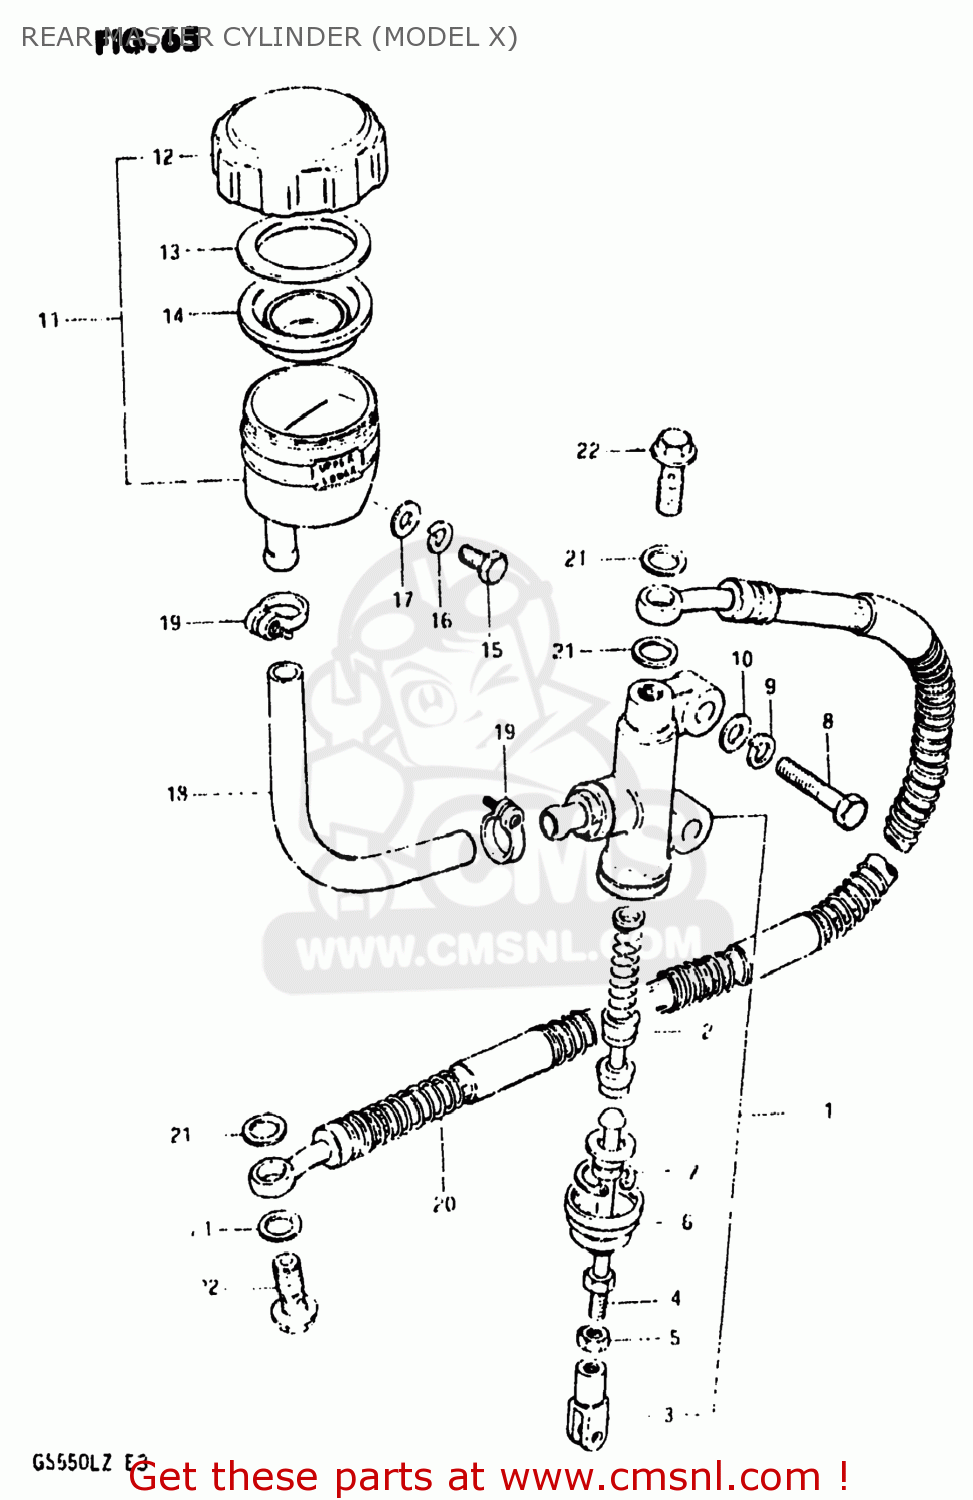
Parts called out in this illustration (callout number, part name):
1	CYLINDER ASSEMBLY,REAR MASTER
2	PISTON/CUP SET
3	YOKE
4	ROD,PUSH
5	NUT
6	BOOT
7	CIRCLIP
8	BOLT (8X30)
9	LOCK WASHER
10	WASHER
11	TANK ASSEMBLY,RESERVOIR
12	CAP
13	PLATE,DIAPHRAGM
14	DIAPHRAGM
15	BOLT, UPPER
16	LOCK WASHER
17	WASHER
18	HOSE,RESERVOIR TANK
19	CLAMP
20	HOSE,REAR BRAKE
21	WASHER
22	BOLT,UNION
